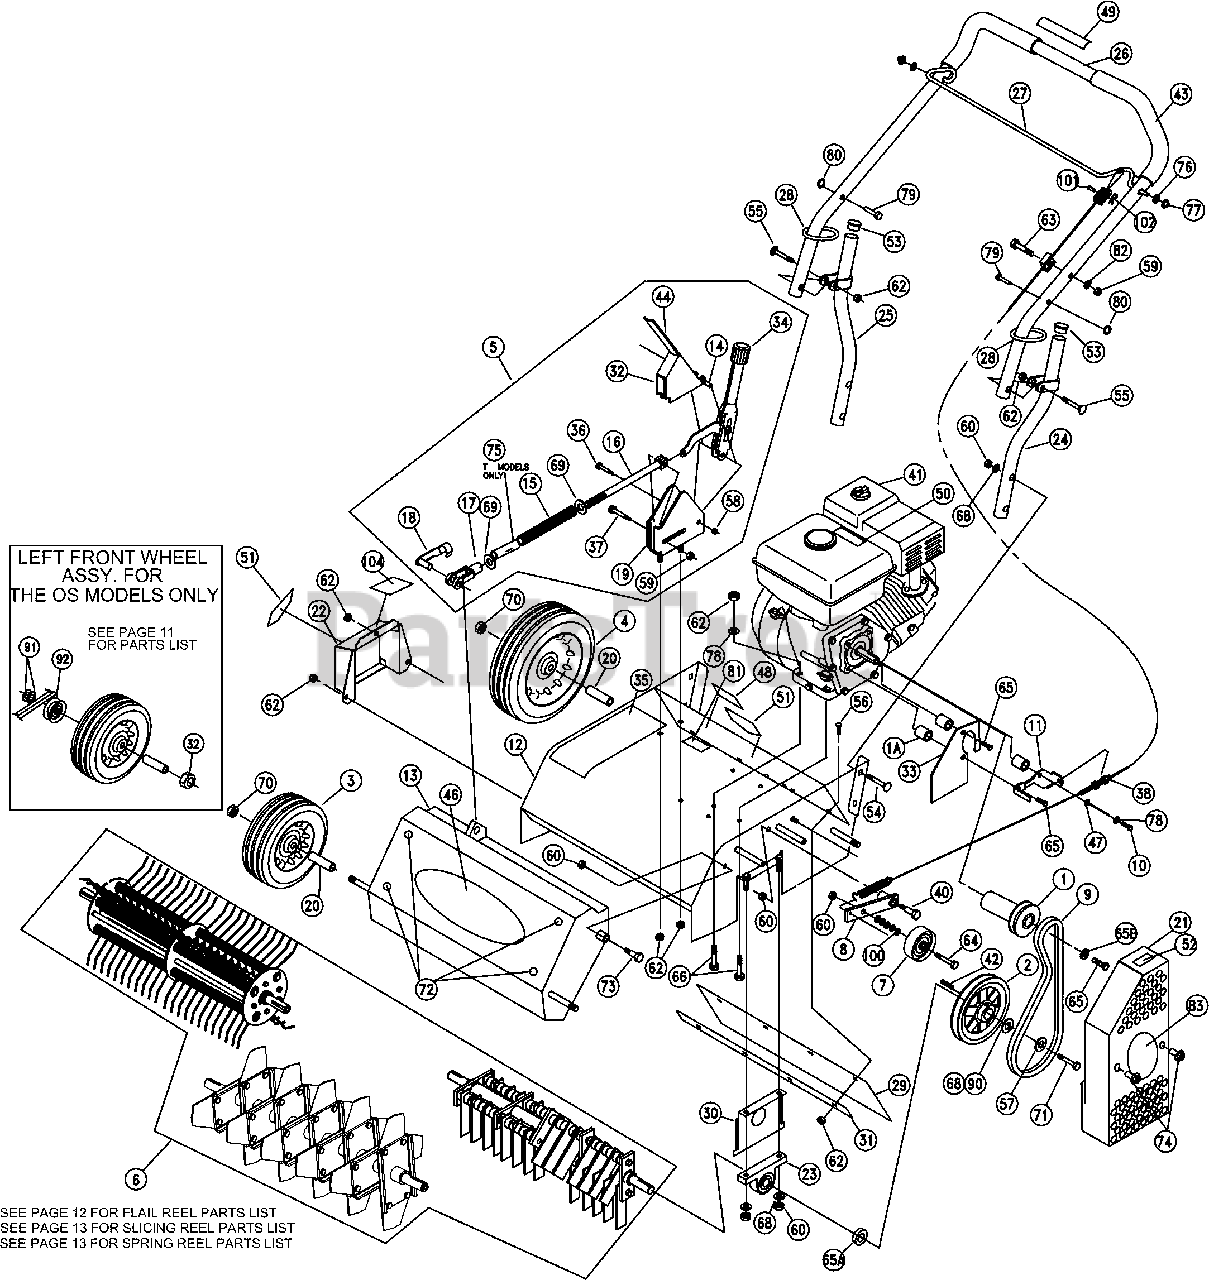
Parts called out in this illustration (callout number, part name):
1	PULLEY PR550/0S550
1A	Spacer 5/8 OD X 3/8 ID X 1.0 LG
2	Pulley 6.5" OD X ¾"
3	WHEEL 8.0" X 5/8" BEARING
4	WHEEL 10.0" X 5/8" BEARING
5	Height Adjust Assy
6	Reel Flail / Slicing / Spring Assy
7	Pulley Idler 2.75"
8	Arm Idler WA
9	Belt 5L X 36
10	Screwcap 5/16" x 24 x 1 1/2 Gr5 HCS
11	Bracket Mount Clutch Cable
12	Chassis WA W/ Label
13	Frame Front WA
14	Bushing 0.375 OD X 0.256 ID X 0.88
15	Spring Height Adjust PR500
16	Link Height Adjust PR500
17	Yoke ½ - 20
18	Pin Yoke ½"
19	Bracket Mount Hgt. Adj. WA
20	Spacer Spanner Wheel PR500
21	Guard Belt WA W/ Label
22	Guard Shaft WA W/ Label
23	Bearing ¾" Cast Pillow Block
24	Handle Lower LH WA
25	Handle Lower RH WA
26	Handle Upper PR500
27	Bail Clutch WA
28	Loop Folding Handle
29	Deflector Rubber
30	Shield Bearing
31	Bar Clamp Deflector
32	Bracket Height Adjust Lock WA
33	Guard Pulley Back
34	Lever Height Control
35	Label Instr. Hgt. Adj.
36	Bolt Shoulder ¼" x 1 ¾"
37	Bolt Shoulder 5/16" x 1 ¾"
38	Cable Clutch PR
40	BOLT SHOULDER 1/2" X 1"
41	ENGINE HONDA 5.5 H.P. GX160
42	KEY 3/16" X 1"
43	GRIP 1" x 13"
44	GRIP LEVER 1/8 x 1 x 5"
46	LABEL PR BADGING
47	FINGER BELT WIRE
48	LABEL DANGER THROWN OBJECT
49	LABEL CLUTCH VQ
51	LABEL WARNING
52	LABEL DANGER GUARD
53	PLUG CAP 1" RD
54	BOLT CARRAIGE 3/8-16 x 1 3/4
55	BOLT CARRAIGE 5/16-18 x 1 3/4
56	BOLT CARRIAGE 5/16 -18 x 3/4
57	WASHER LOCK 3/8" S/T MED
58	NUT LOCK #10-24
59	NUT LOCK 1/4-20
60	NUT LOCK 3/8-16
62	NUT LOCK 5/16-18
63	SCREWCAP 1/4-20 x 1 1/2
64	SCREWCAP 3/8 - 16 x 1 3/4
65	SCREWCAP 5/16-24 x 3/4" GR.5
65B	Washer 5/16 Twist Tooth
66	SCREWCAP 5/16 - 18 x 1 1/2
68	WASHER 3/8 FLAT CUT
69	WASHER 1/2 SAE ZP
70	NUT LOCK 1/2" - 13 THIN HGT
71	SCREWCAP 3/8" - 16 X1" HCS ZP
72	BUTTON SOCKET 5/16-18X5/8”
73	BOLT SHOULDER 1/2" x 2"
74	FLANGE SCREW 0.375 -16 X 0.75
76	WASHER 3/8 SAE
77	NUT PAL 3/8
78	WASHER 1/4 FLAT CUT
79	PIN CLEVIS 3/8" X 1.625
80	RETAINER 3/8" BOLT PUSH NUT
81	LABEL SPARK ARRESTOR EN/SP
82	WASHER 1/4 SAE
83	LABEL LOGO PRODUCT SM CIRCLE
100	WASHER FLAT 5/16"
101	SCREW MACH #10-24 X 5/8" HWF ZP
102	NUT LOCK #10-24 HEX
104	LABEL MADE IN U.S.A.
